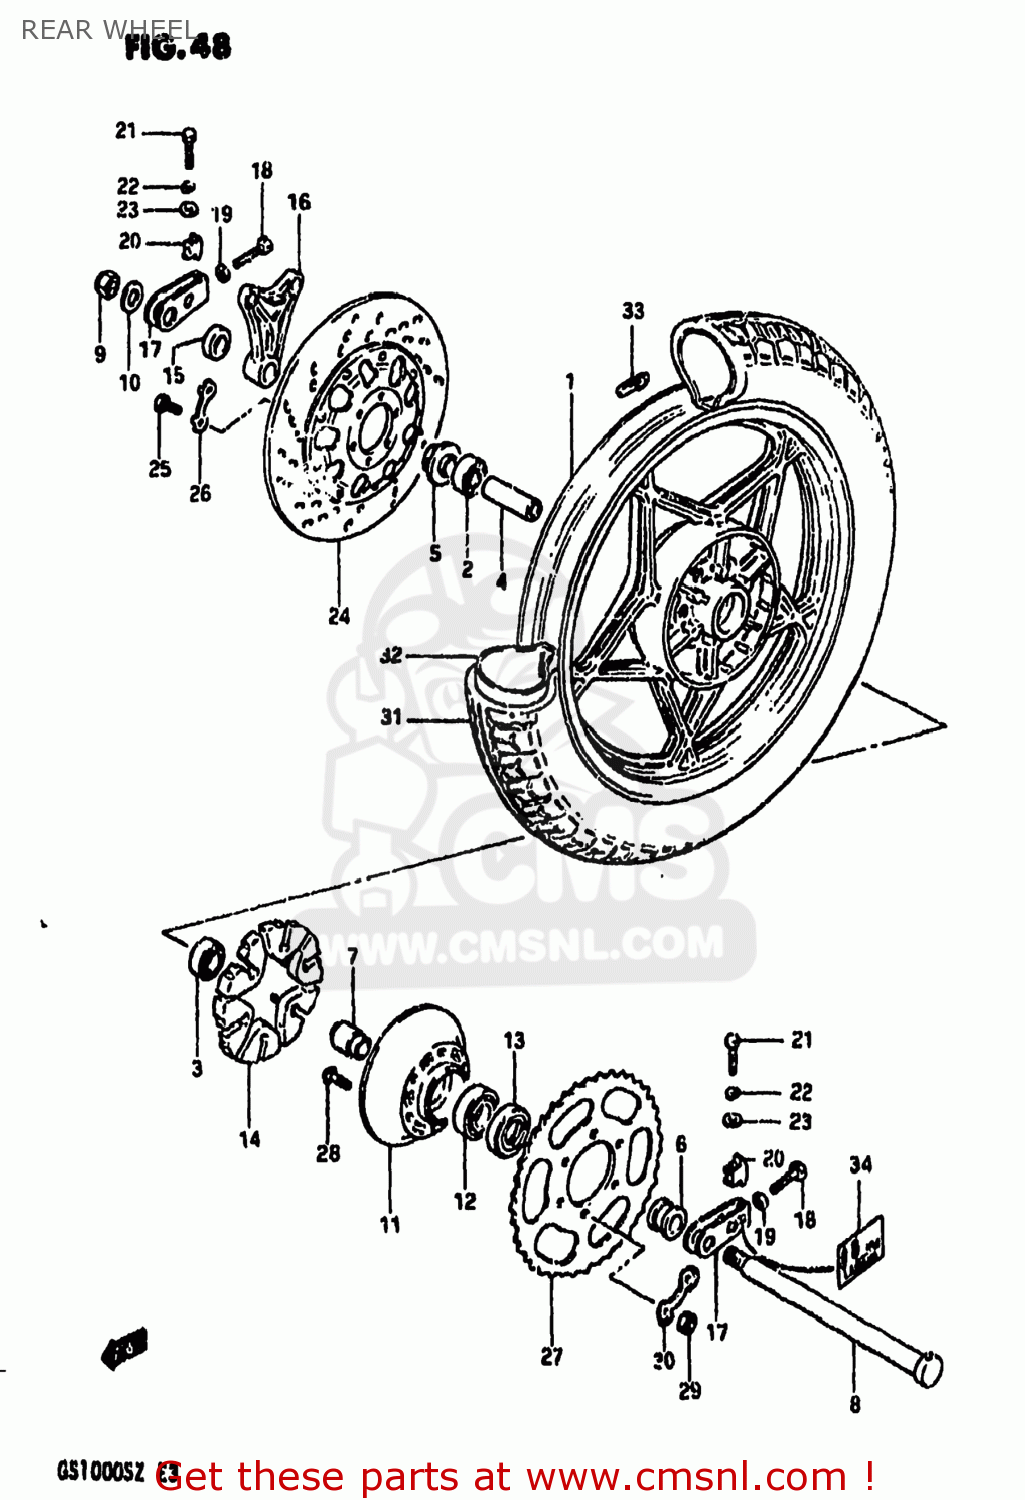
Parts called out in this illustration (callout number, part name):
1	WHEEL,RR(17XMT2.50)
2	BEARING WHEEL REAR(20X47X14)
3	BEARING, LH
4	SPACER(20.5X28X88)
5	SPACER,REAR AXLE
6	SPACER(20X33X28.3)
7	SPACER,REAR HUB BEARING
8	AXLE,REAR
9	NUT
10	WASHER(19X34X4)
11	DRUM,REAR SPROCKET MOUNT
12	BEARING
13	SEAL,OIL(33X62X7)
14	ABSORBER,REAR HUB SHOCK
15	SPACER(20X38X12)
16	BRACKET,RR,CALIPER
17	ADJUSTER,CHAIN
18	BOLT
19	NUT
20	SUPPORTER,CHAIN ADJUST
21	BOLT
22	LOCK WASHER
23	WASHER
24	DISC,RR BRAKE
25	BOLT(8X30)
26	WASHER
27	SPROCKET,REAR
28	BOLT
29	NUT
30	WASHER
31	TIRE 4.50V17
32	TUBE ASSEMBLY,WHEEL,INNER
33	BALANCER,WHEEL
34	LABEL,CHAIN WEAR INDICATOR
